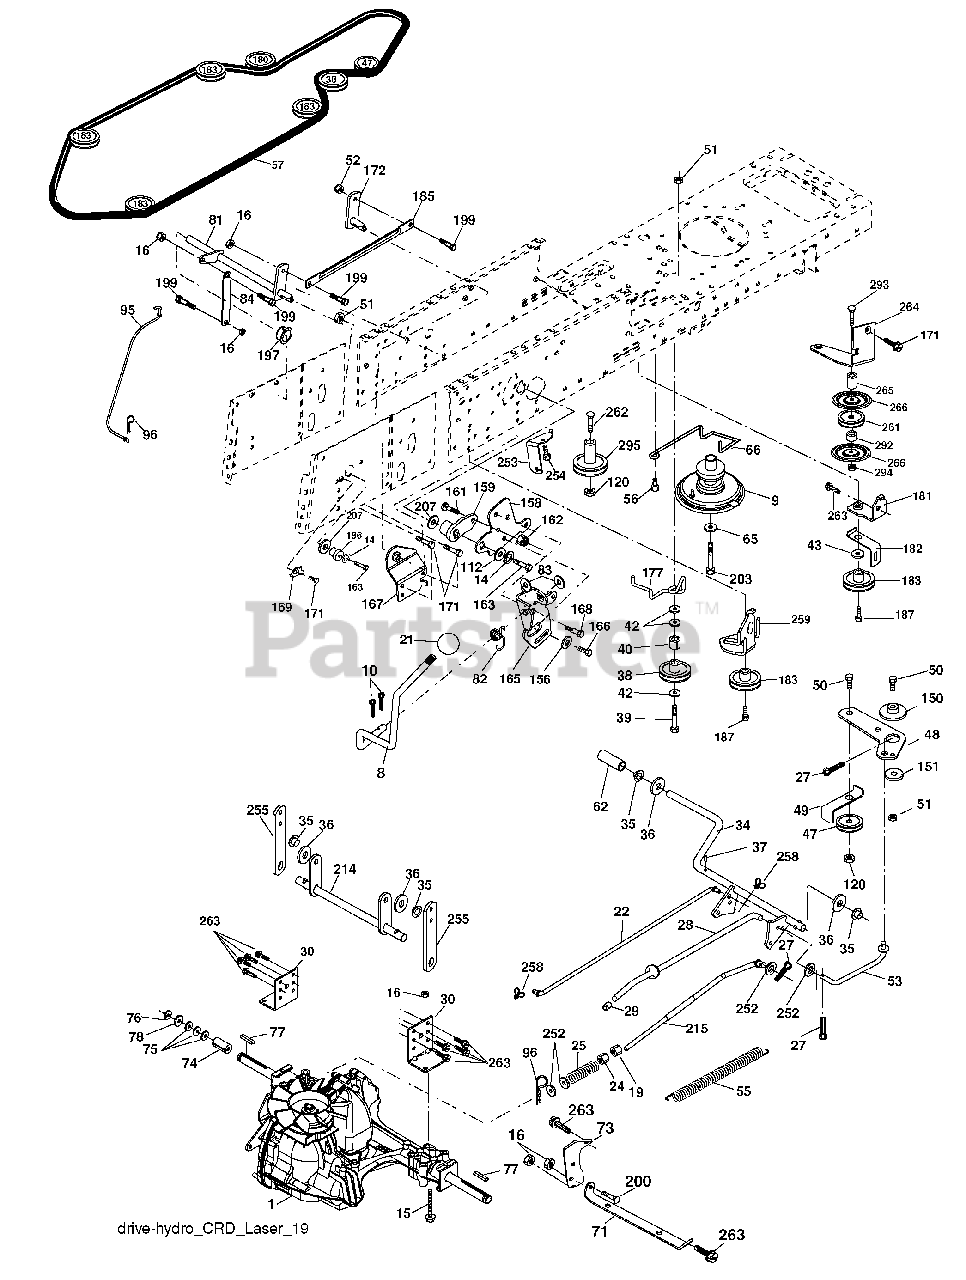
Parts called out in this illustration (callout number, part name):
8	Rod, Shift Fender Adjust Lt
9	Clutch Asm Noram
10	Pin, Cotter 1/8 x 1
14	Washer, Lock Hvy Helical
15	Bolt Hex FGHD 5/16-18 x Gr. 5
16	Nut Lock Hex W/Ins 5/16-18 unc
19	Nut Lock Hex w/Insert 3/8-16 unc
22	Rod, Brake
24	Nut
25	Spring, Rod, Brake
26	Washer 13/32 x 13/16 x 16 Ga.
27	Pin, Cotter 1/8 x 3/4
28	Rod, Parking Brake
29	Cap, Parking Brake
30	Bracket, Mfg. Transaxle
34	Shaft, Asm Pedal Foot CRD
35	Bearing, Nylon
36	Washer 21/32 x 1 x 16 Ga.
37	Pin, Roll 3/16 x 1"
38	Pulley Flat Composite 3.06"
39	Bolt Fin Hex 3/8-16 unc x 2-3/4
40	Spacer, Split 395 x 59 Bzp
42	Washer 13/32 x 13/16 x 12 Ga.
43	Washer 11/32 x 5/8 x 12 Ga.
47	Pulley, Idler, V Groove Plasitc
48	Bellcrank Clutch Grnd Drv
49	Retainer, Belt Style Spring
50	Bolt 3/8-16 x 1-1/2 Gr. 5
51	Nut, Crownlock 3/8-16 unc
52	Nut Crownlock 5/16-18
53	Link, Clutch 7.66
55	Spring, Return, Clutch
56	Screw 3/8-16 x 1-1/4
57	V-Belt Kev 112" 0650 CRD
62	Cover, Pedal
65	Washer
66	Keeper, Belt Engine F-Proof
71	Strap, Torque, Lh
73	Strap, Torque, Rh
74	Spacer, Split
75	Washer 25/32 x 1-1/4 x 16 Ga.
78	Washer 25/32 x 1-5/8 x 16 Ga.
81	Asm, Shaft,Cross Rear
82	Spring, Torsion
83	Washer 17/32 x 3/4 x 16 Ga.
84	Link, Transaxle
95	Control Asm Bypass Hydro
96	Spring, Retainer 1"
112	Washer 9/32 x 3/4 x 10 Ga.
120	Nut Lock Flg. 3/8-16 unc
150	Bushing, Bellcrank Grnd Dr
151	Washer 13/32 x 2 x 10 Ga.
156	Washer Srrted 5/16 ID x 1.125
158	Bracket Shift Mount
159	Hub Shift
161	Bolt Rdhd Sqnk 1/4-20 x 3/4 Gr. 5
162	Nut Crownlock 1/4-20 unc
163	Bolt Hex Fin 1/4-20 unc x 1 Gr 5
165	Bracket Pivot Lever
166	Screw 5/16-18 x 5/8
167	Bracket Support Shift CRD
168	Bolt Shoulder 5/16-18 x .561
169	Plate Fastening Lt
171	Screw Thdrol 3/8-16 x 1/2 Ty-Tt
172	Shaft Asm Shifter Frt CRD
177	Keeper Flat Idler 3.06" CRD
181	Bracket Idler Ground Drive CRD
182	Keeper Belt 2.5" Od V-Idler CRD
183	Pulley V-Idler 2.50" Od CRD
185	Link Shift
186	Hub Tapered Round CRD
187	Screw Thdrol 5/16-18 x 1.25
197	Nyliner Snap-In 5/8
199	Bolt Shoulder 5/16-18 unc
200	Bolt RDHD SQNK 5/16-18 x 1
203	Bolt Hex 7/16-20 x 5
207	Washer Nylon Rear
214	Shaft Asm. Brake
215	Rod Brake Hydro
252	Washer 13/32 x 1 x 16 Ga.
253	Bracket Cable Chassis
254	Screw 3/8-16 x 1
255	Brace Shaft Brake Mtg.
258	Clip Retainer
259	Bracket Pulley
261	Pulley Idler
262	bolt Rdhd 3/8-16 unc x 2-3/4 Gr. 5
263	Screw 3/8-16 x 3/4
264	Bracket Clutch Mounting
265	Spacer Idler Chassis
266	Shield Idler Mower
292	Spacer Noram
293	Bolt Rdhd Sqnk 3/8-16 x 3-1/2
294	Nut Jam 3/8-16
295	Pulley Idler Composite
